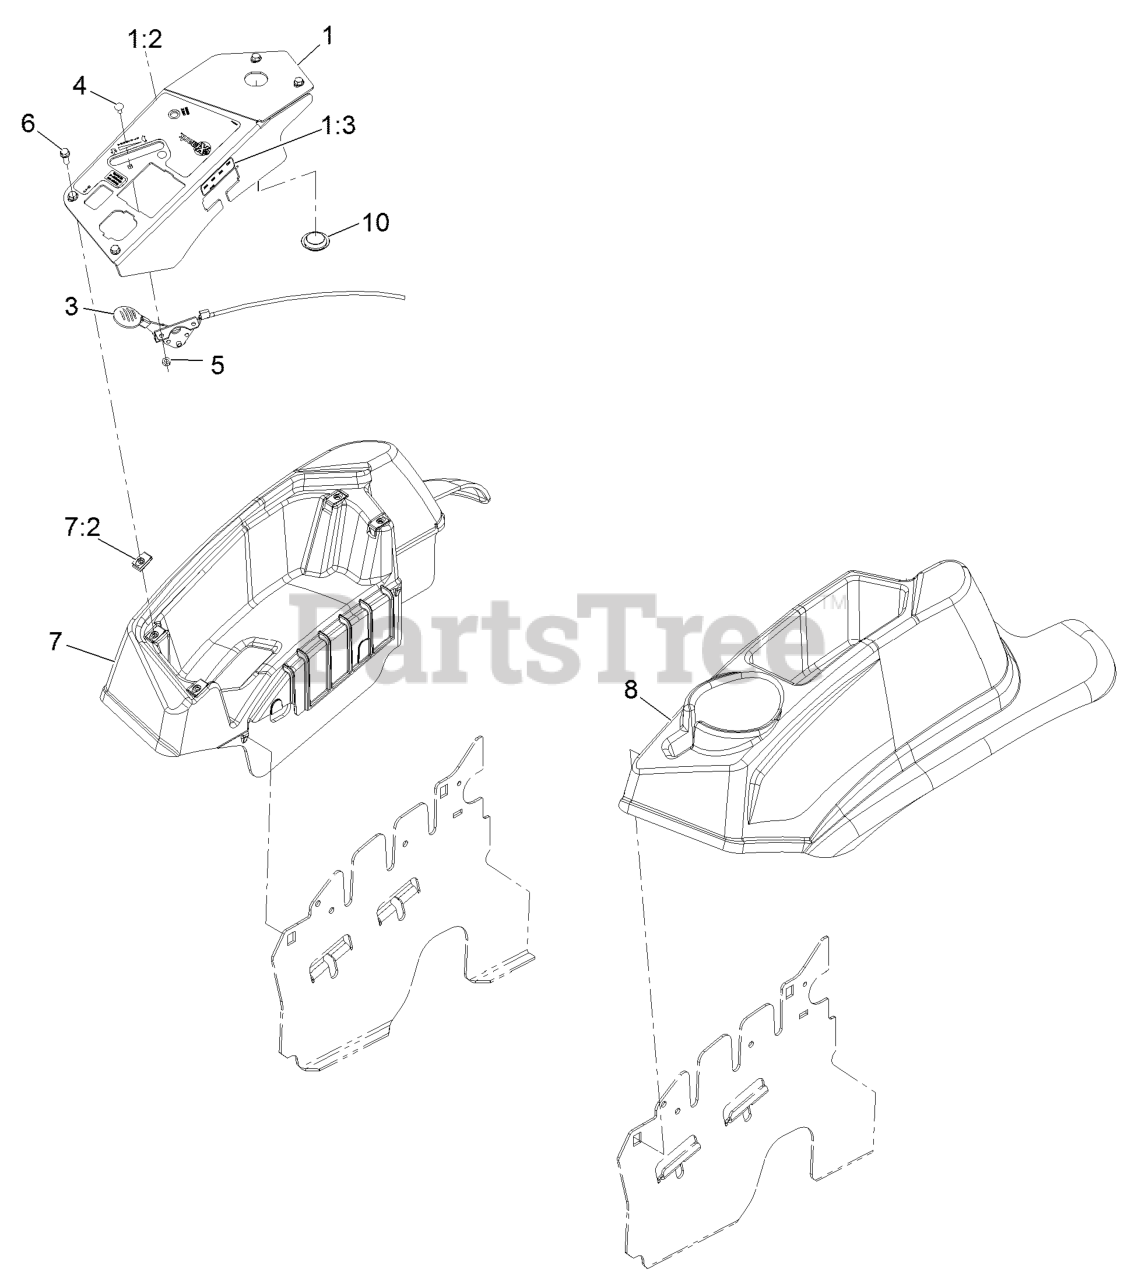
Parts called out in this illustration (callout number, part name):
1	ASM,CONTROL PANEL W/DECAL
1:2	DECAL,CONTROL PANEL EFI
1:3	DECAL-FUSE
3	ASM,THROTTLE CABLE
4	BOLT-CARR
5	NUT-LOCK, NI
6	SCREW-HWH
7	CONSOLE,RH AS ASM
7:2	Nut-Retainer-Panel 1/4-20
8	CONSOLE, LH AS
10	PLUG-PLASTIC
